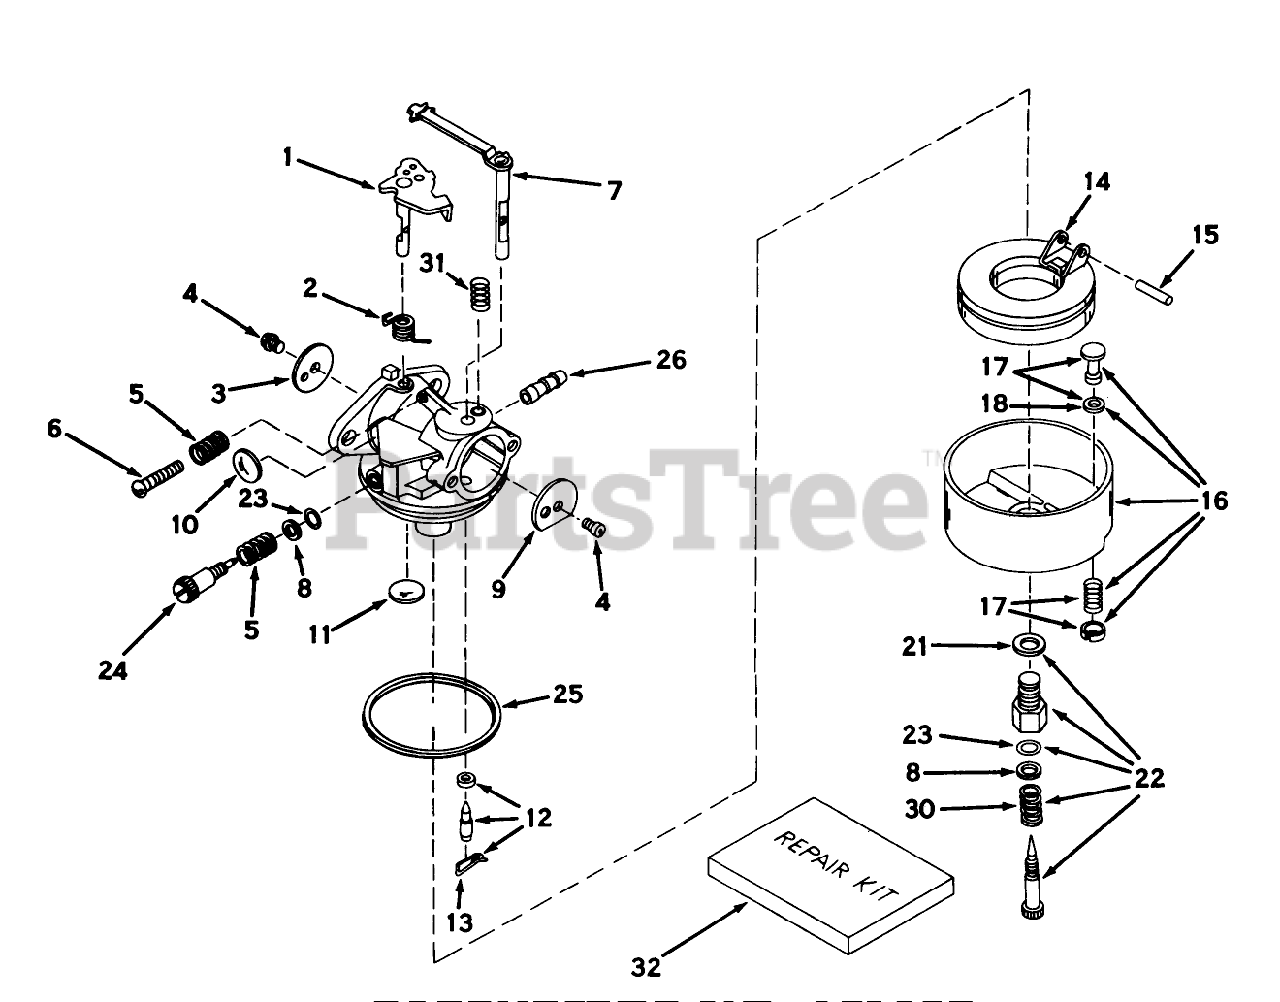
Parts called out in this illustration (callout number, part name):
1	Shaft/Lever-Throttle
2	Spring, Return
3	Shutter-Throttle
4	Screw-Shutter
5	Spring-Tension
6	Screw-Throttle Crack Screw / Idle Speed
7	Shaft Lever Ass-y Choke
8	Washer
10	Plug-Welch, Idle Mixture Well
11	Plug-Welch, Atmospheric Vent
12	Inlet Needle, Seat Clip Assy. (Incl. No. 13)
13	Clip-Spring
14	Float,Carburetor
15	Shaft-Float
16	Bowl Drain Assy., Float (Incl. No. 17)
17	Bowl Drain ASM
18	Gasket-Plunger, Drain
21	Washer-Bowl Nut
22	Adjustment Screw Assy., Main (Incl. Nos. 5A, 21 23)
23	ORing
24	Screw, Idle Adj.
25	O Ring-Bowl, Float
26	Fitting, Fuel Inlet
30	Spring
31	Spring-Positioning, Choke
32	Repair Kit (Incl. items marked *)
